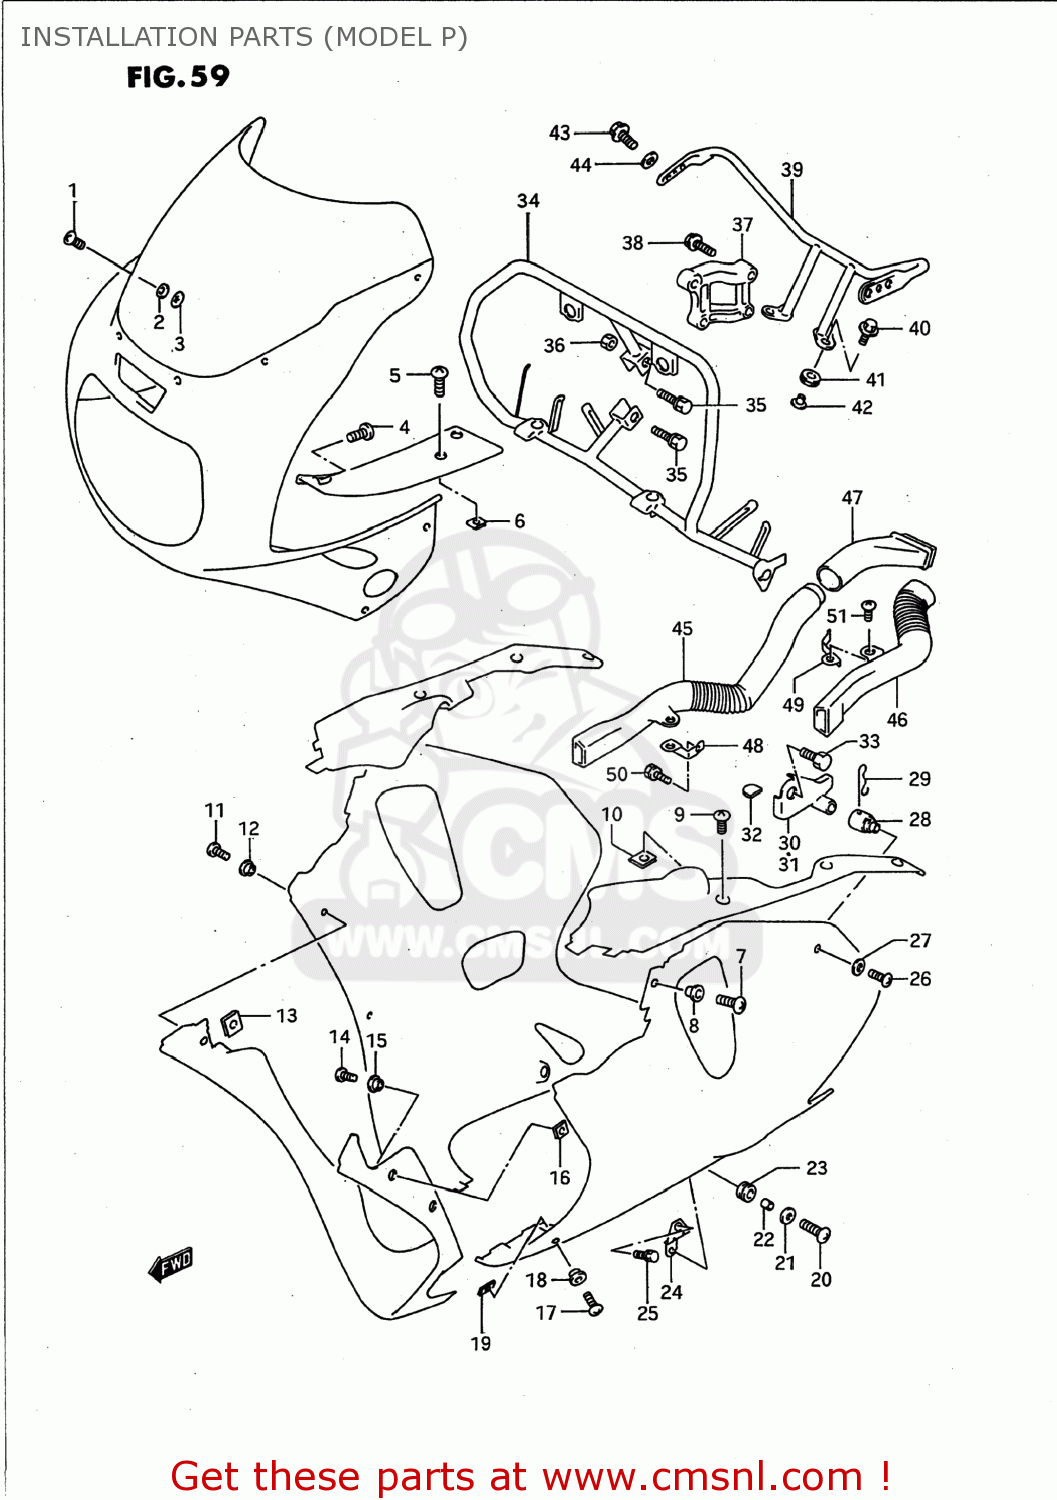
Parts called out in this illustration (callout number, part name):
1	PIN,WINDSCREEN
2	CUSHION
3	NUT
4	SCREW, FRONT & REAR
5	SCREW
6	NUT
7	SCREW(5X18)
8	WASHER(5.2X14X1.5)
9	SCREW
10	NUT
11	SCREW(5X18)
12	WASHER(5.2X14X1.5)
13	NUT,RH & CTR UNDER COWLING
14	SCREW
15	WASHER(5.2X14X1.5)
16	NUT
17	SCREW(5X18)
18	WASHER(5.2X14X1.5)
19	NUT,RH & CTR UNDER COWLING
20	SCREW(6X25)
21	WASHER(6.5X18X1)
22	SPACER (6.1X9X10)
23	CUSHION
24	BRACKET,UNDER COWLING
25	BOLT
26	SCREW(6X20)
27	WASHER
28	PLUG,UNDER COWL FTG,CTR
29	PIN,UNDER COWLING FITTING PIPE
30	BRACE,UNDER COWLING,UPPER
31	BRACE,UNDER COWLING,UPPER
32	CUSHION,UPR BRACE
33	BOLT, BRACKET (6X12)
34	BRACE,COWLING
35	BOLT,BRACE (8X30)
36	NUT 8MM
37	BRACE,COWLING CTR
38	BOLT,BRACE (8X40)
39	BRACE,RR VIEW MIRRORR
40	BOLT 6X20
41	CUSHION
42	WASHER
43	SCREW(6X12)
44	WASHER(6.2X19X1.5)
45	PIPE,AIR INTAKE FR,R
46	PIPE,AIR INTAKE FR,L
47	PIPE,AIR INTAKE RR,R
48	JOINT,AIR INTAKE
49	BRACKET,AIR INTAKE,LEFT
50	BOLT, BRACKET (6X12)
51	SCREW 6X12
